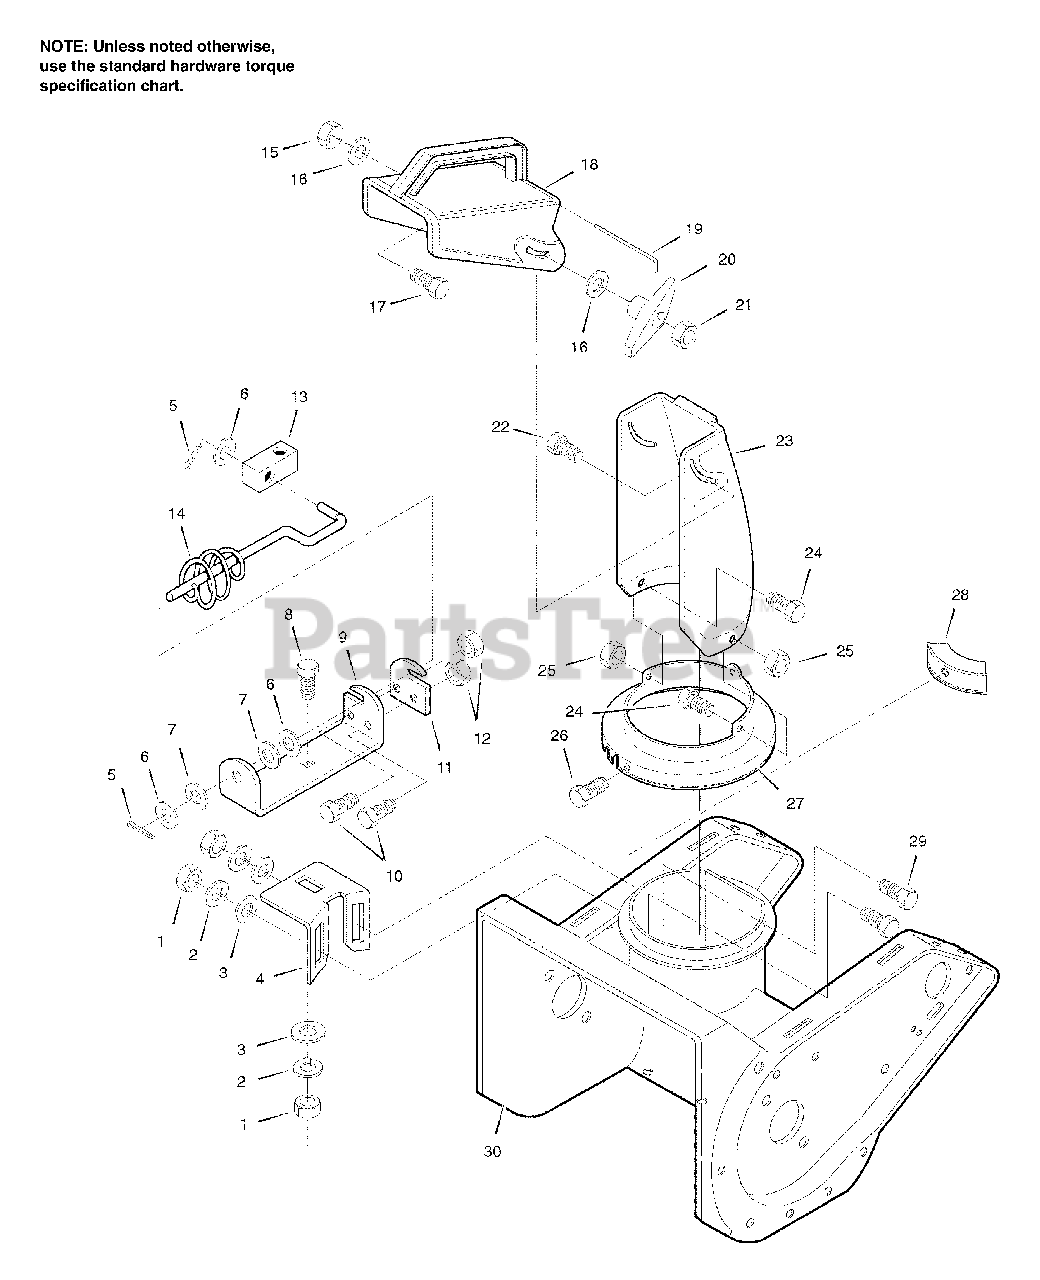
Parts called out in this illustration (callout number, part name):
1	NUT, .31-18 HEX
2	WASHER, LOCK
3	WASHER, FLAT .349-0.69-.07
4	BRKT, WORM ADJUST
5	PIN, COTTER.094 x 0.75L
6	WASHER, FLAT .400-0.75-.02
7	WASHER, SPRING .395-0.73-.01
8	BOLT, CARRIAGE .31-18 x 0.75
9	BRACKET, CHUTE ROD HOLE
10	SCREW, .25-20 x 0.50 Hex Head Cap
11	PLATE, CHUTE ROD
12	NUT, LOCK .25-20 Hex
13	BLOCK, PIVOT CHUTE
14	ROD ASSEMBLY, LOWER CHUTE
15	NUT, LOCK .31-18 HEX
16	WASHER, FLAT .349-0.69-.07
17	SCREW, .31-18 x 0.75
18	CHUTE, UPPER
19	WIRE FORM, HINGE
21	NUT, .31-18 HEX
22	BOLT, CARRIAGE .31-18 x 1.50
23	CHUTE, LOWER
24	SCREW, .25-20 x 0.50
25	NUT, LOCK .25-20
26	SCREW, .25-14 x 0.62
27	CHUTE RING
28	CLIP, CHUTE RING
29	BOLT, CARRIAGE .31-18 x 0.75
30	AUGER HOUSING, 21"
